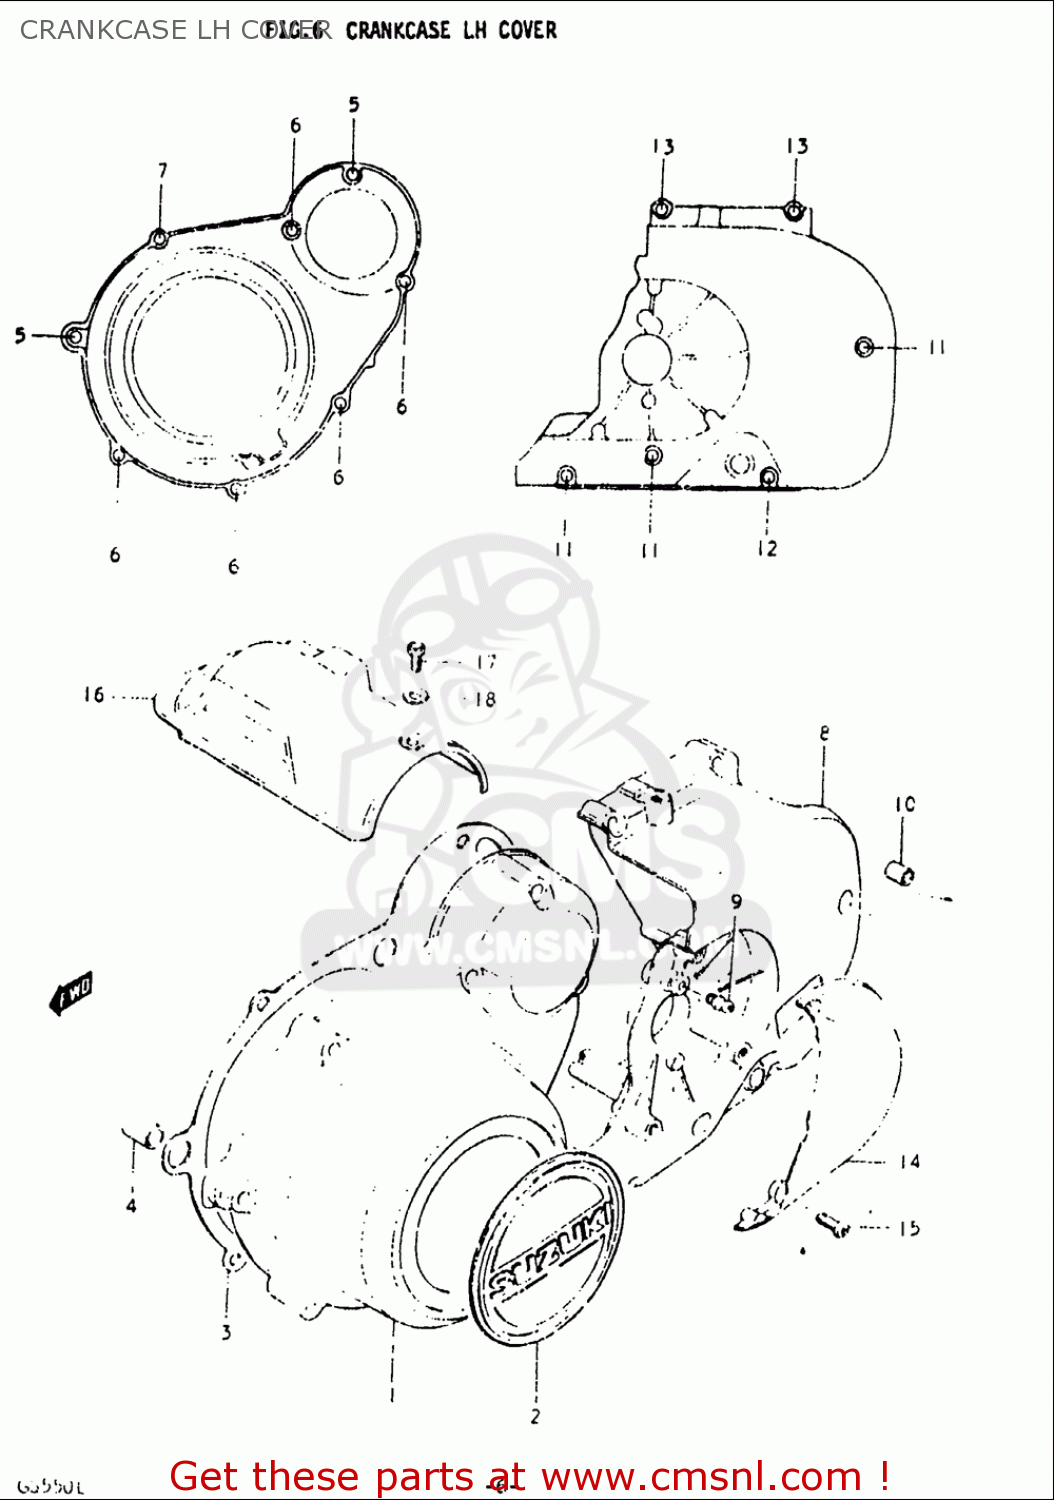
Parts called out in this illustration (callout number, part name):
1	COVER,MAGNETO
2	EMBLEM,MAGNETO COVER
3	GASKET,MAGNETO COVER (NAS)
4	PIN
5	SCREW
6	SCREW
7	SCREW
8	COVER SET,ENGINE SPROCKET
9	NIPPLE
10	PIN
11	SCREW
12	SCREW
13	SCREW
15	SCREW
16	COVER,STARTER MOTOR
17	BOLT
18	WASHER
